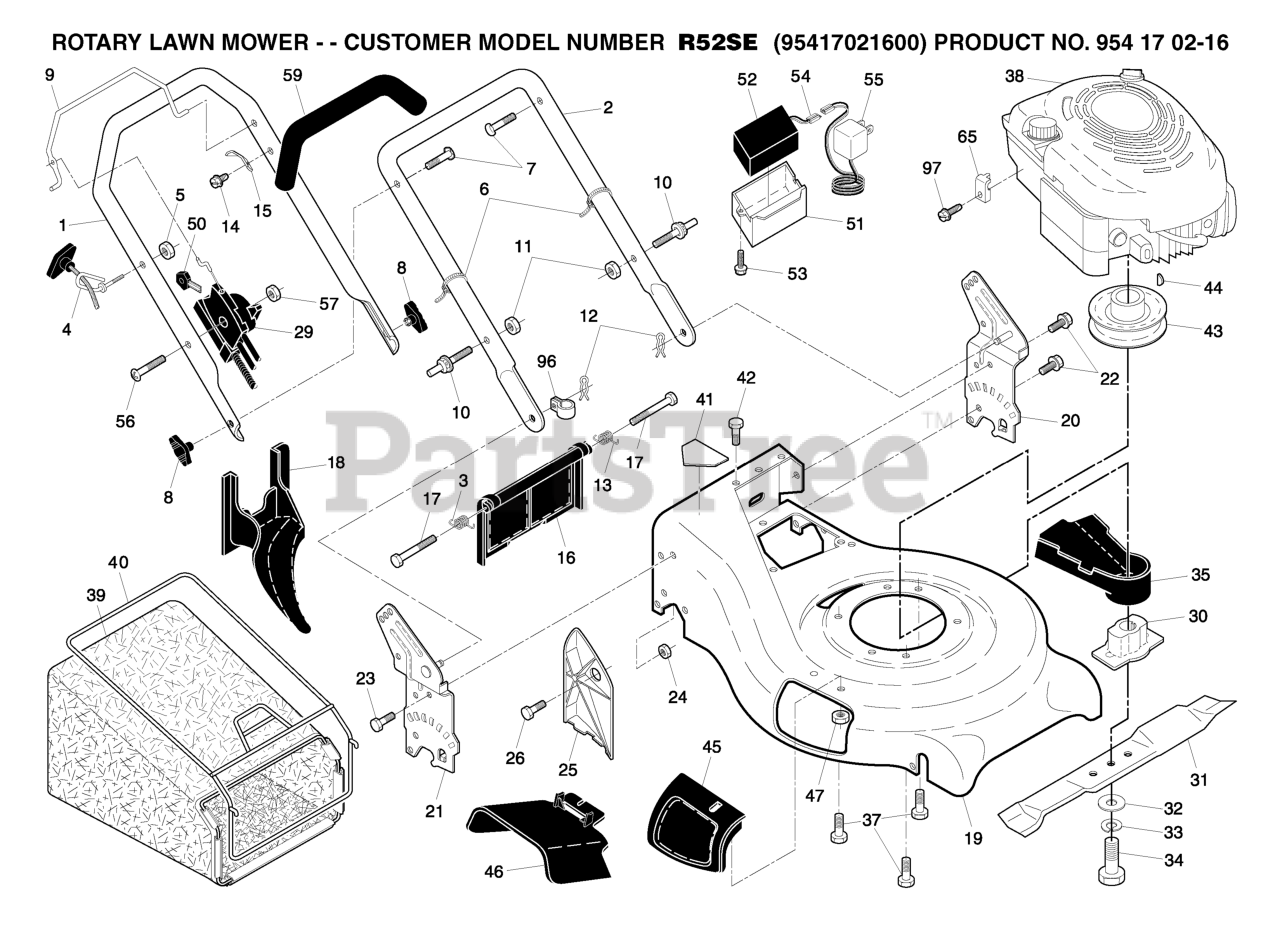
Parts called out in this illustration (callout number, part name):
1	HANDLE.UP.DLX.COMF.W/GRIP.GREY
2	HANDLE LOWER
3	SPRING.LH.REAR.DOOR.21.RWGD
4	ROPE, GUIDE
5	NUT
6	TIE GUIDE
7	BOLT, HANDLE 5/16-18X1.75
11	NUT.CENTERLOCK.5/16-
12	HAIRPIN COTTER
13	SPRING.RH.REAR.DOOR.21.RWGD
14	BRACKET UPSTOP
16	DOOR.REAR.PLASTIC.21.RWGD.BLAC
18	PLUG, MULCHER
20	BRKT.ASM.HNDL.21.RWGD.LT
21	BRKT.ASM.HNDL
22	SELF-TAPPING SCREW 5/16-18X3/4
23	BOLT, HEX HEAD 5/16-18
24	NUT.71038.31-18.HEX.NYLOCK
25	CLIPPING DEFLECTOR
29	CONTROL.ELECTRIC.KEY.START
30	BLADE ADAPTER
32	WASHER,HARDEN
33	LOCKWASHER
34	SCREW, HEX HD 3/8-24 X 1-3/8
37	BOLT 3/8-16X1-1/8
40	GRASS CATCHER FRAME
41	DECAL.INTERNATIONL.CUTFINGER
43	PULLEY.ENG.25MMM
44	HI-PRO KEY
45	MULCHER DOOR ASM.
46	DEFLECTOR, DISCHARGE
50	KEY.MOLDED.GENERIC
52	KIT BATTERY REPL
53	SCREW.HX.13X.750
54	CONNECTOR PM
55	BATTERY CHARGER
57	LOCK NUT
59	GRIP.HANDLE.FOAM
65	CABLE CLAMP(ENGINE)
96	CLIP.CABLE.BLK
97	SCREW.HEX.HEAD.WASHER.10-16
